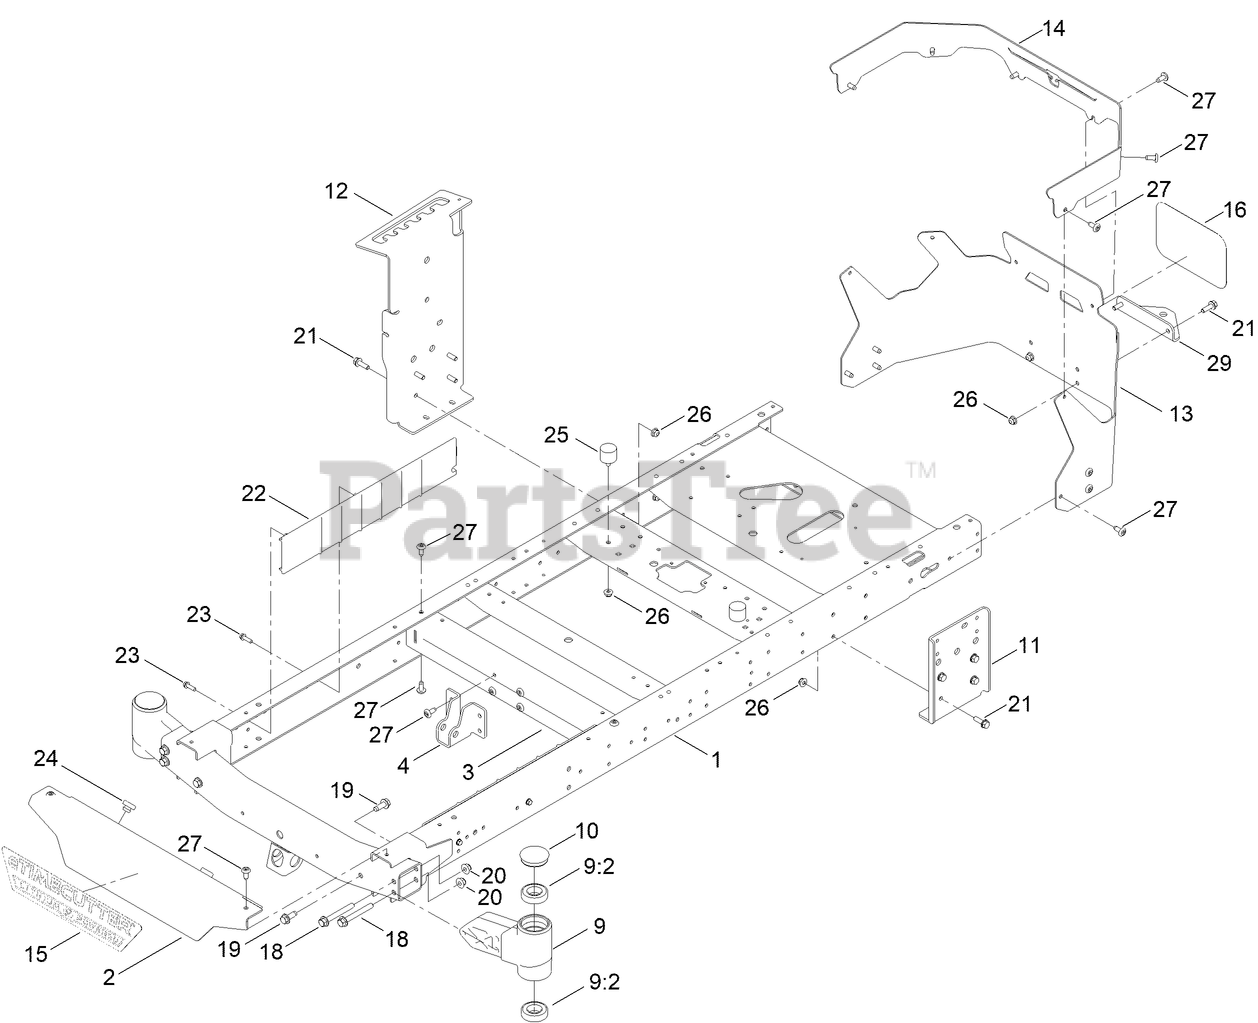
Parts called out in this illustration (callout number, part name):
1	FRAME ASM [RED]
2	FOOTREST
3	BRACE-CROSS, LOWER
4	BRACKET-MOUNT DAMPER, LOWER
9	AXLE STUB ASM
9:2	BEARING-BALL
10	CAP-GREASE
11	PLATE-MOUNT, DRIVE
12	PLATE-MOUNT, MR DRIVE
13	GUARD-REAR
14	GUARD-REAR, UPPER
15	DECAL-ETIMECUTTER
16	DECAL-LOGO, SILVER
18	SCREW-HHF
19	SCREW-HWH
20	NUT-HF, NI
21	SCREW-HHF
22	GUARD-RAIL
23	SCREW-PLASTITE, HWH
24	BUMPER-RUBBER
25	BUMPER-RUBBER
26	NUT-HF
29	BRACKET-HITCH
